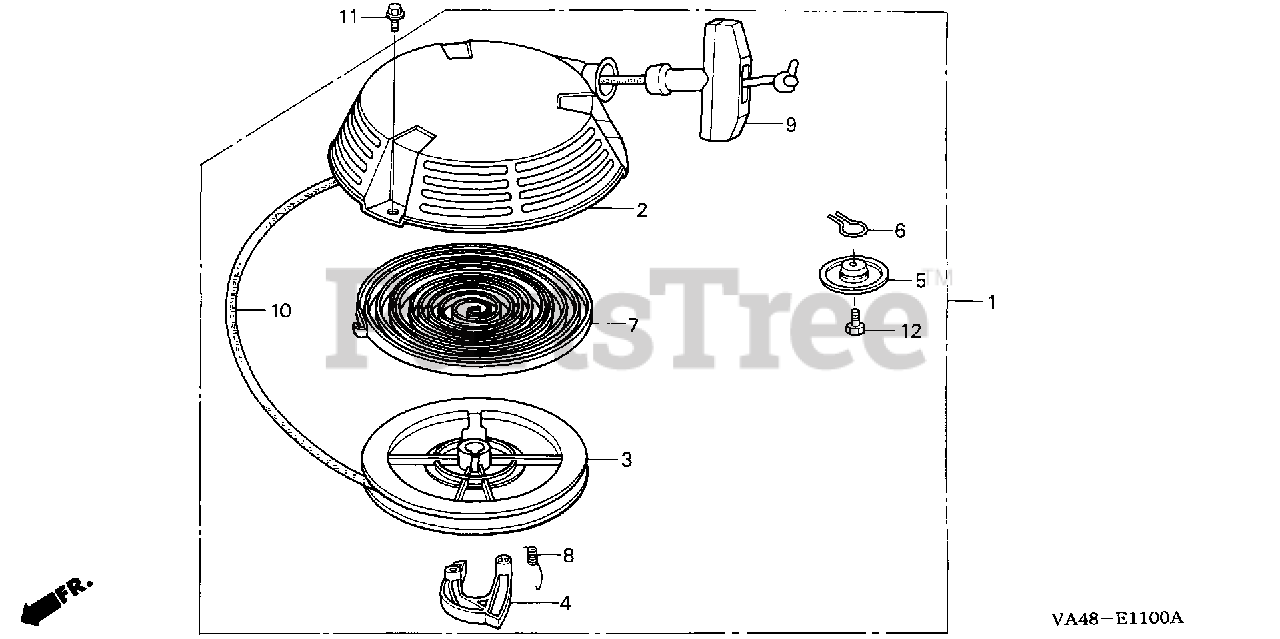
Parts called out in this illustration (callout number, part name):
1	STARTER ASSY., RECOIL *R8* (BRIGHT RED)
1	STARTER ASSY., RECOIL *R280* (POWER RED)
2	CASE, RECOIL STARTER *R8* (Honda Code 3352754). (BRIGHT RED)
3	PULLEY, RECOIL STARTER
4	RATCHET, STARTER
5	PLATE, FRICTION
6	SPRING, FRICTION
7	SPRING, RECOIL STARTER
8	SPRING, RETURN
9	KNOB, RECOIL STARTER
10	ROPE, RECOIL STARTER (#4X55")
10	ROPE, LONG (55")
11	BOLT, FLANGE (6X8)
12	BOLT, HEX. (6X20)
